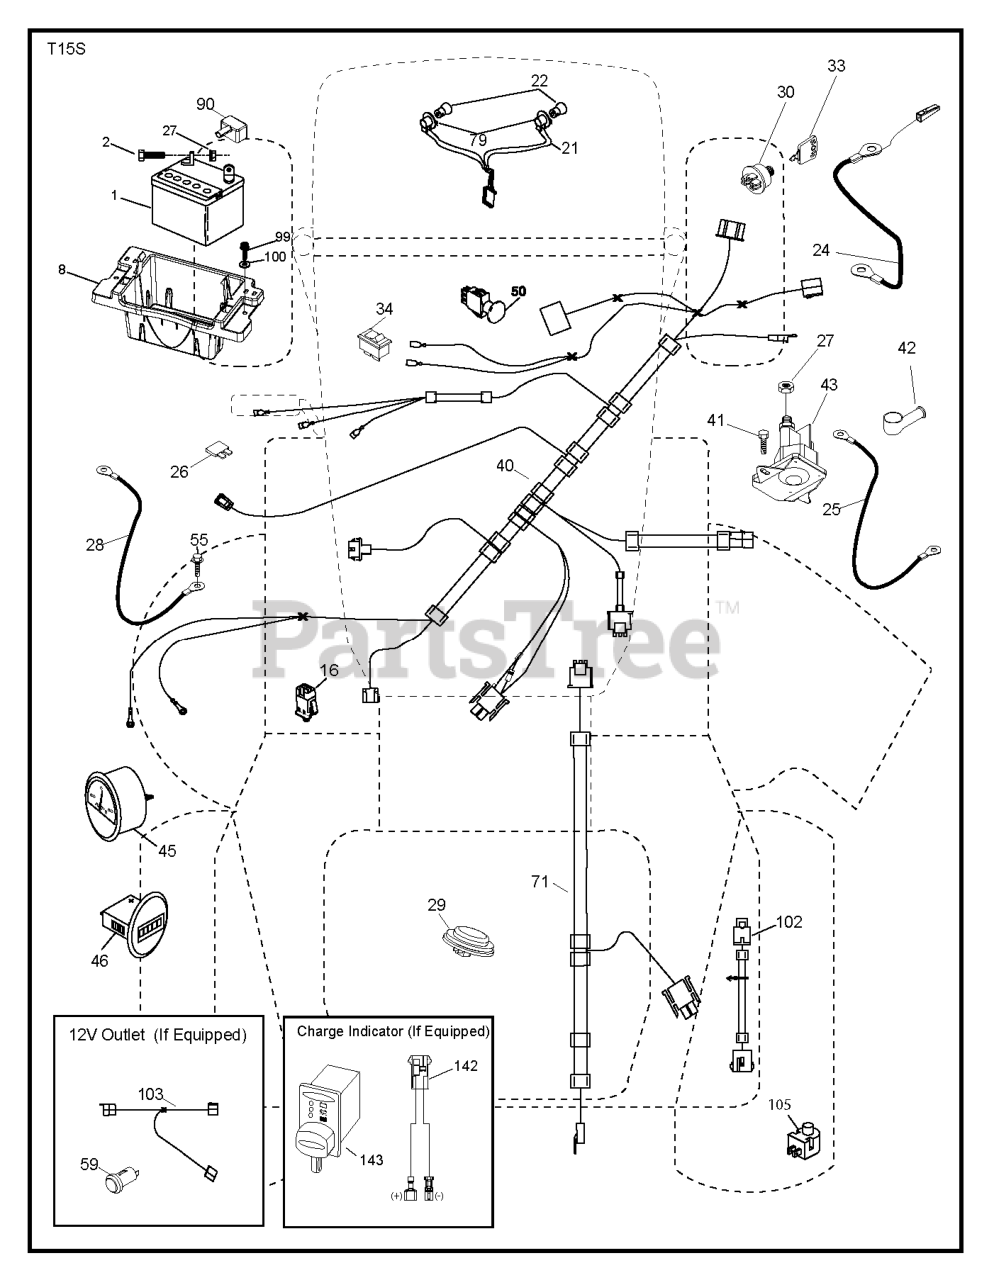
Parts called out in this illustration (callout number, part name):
1	Battery, Dry 30 Amp
2	BOLT.HEX.1/4.X.3/4.DICHROMATE
8	TRAY.BATTERY.FRONT.CARB
16	SWITCH INTERLOOK PUSH-IN
21	HARNESS.LIGHT W/4152J BULBS
24	CABLE.FRBATT.W/WIRE.8GA.8
25	CABLE.STARTER.8GA.17.5
26	FUSE 20AMP
27	NUT
28	CABLE.GROUND.21"BLK.8GA.90T
29	SWITCH.SEAT.DELTA.OPC.
30	SWITCH.IGN.DELTA.W.LGH.ROS
33	KEY.CHAIN.BLISTER.PACK.GEN.USA
40	HARNESS.IGN.DSH.W112V.WPORTWIR
41	SCREW
42	TERMINAL COVER
43	SOLENOID.W/BRASS.PLUNGER
45	GAUGE.AMMETER.SILVER/WHITE
46	GAUGE.HOUR.METER.SILVER/WHITE
50	RP.PTO.SWITCH.8 TERMINAL.BLACK
55	SCREW 5/16"
59	OUTLET.12-VOLT
71	HARNESS-CHASSIS SUB
79	BULB HOLDER ASM.
90	COVER.TERMINAL.BATTERY
91	STRAP.BATTERY.MOUNT.FRONT(2 2)
99	SCREW HEXWSHR 1/4-20X3/4
100	WASHER
102	HARNESS PIGTAIL PCH TEX ROS
103	HARNESS.PIGTAIL.12V.OUTLET.
105	REVERSE SWITCH
142	CHARGE.PORT.PIGTAIL HARNESS
143	CHARGE.PORT
